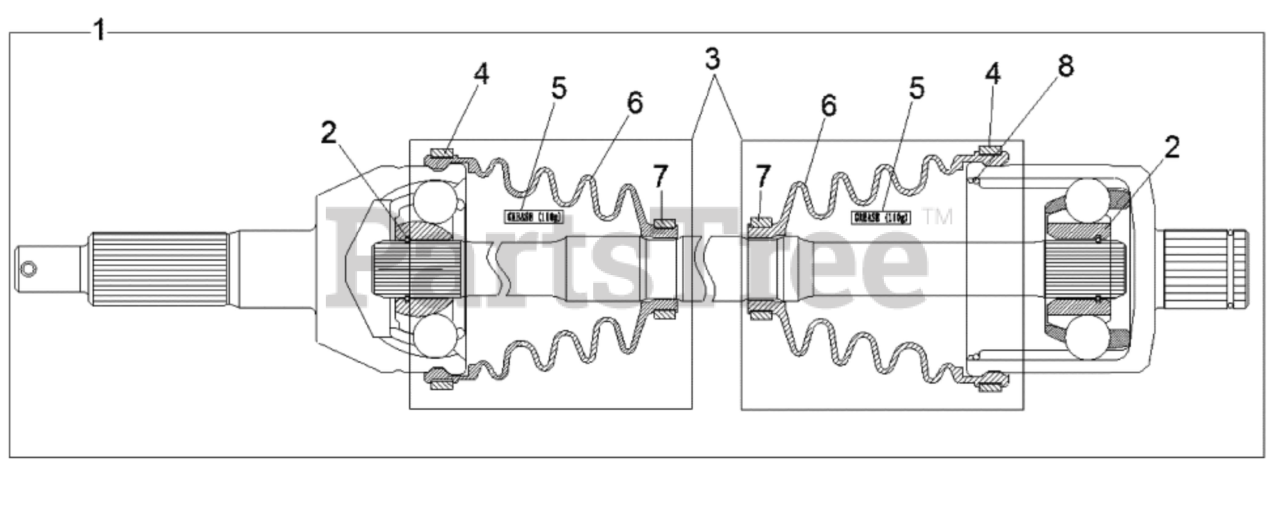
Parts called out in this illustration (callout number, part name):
1	ASM-DRIVESHAFT,REAR
2	CIRCLIP
3	KIT-BOOT(PR-8071)
4	CLAMP-LARGE(PR-0027)
5	GREASE(K575/VW738)
6	BOOT(PR-0025)
7	CLAMP-SMALL(PR-0026)
8	RING, RUBBER
